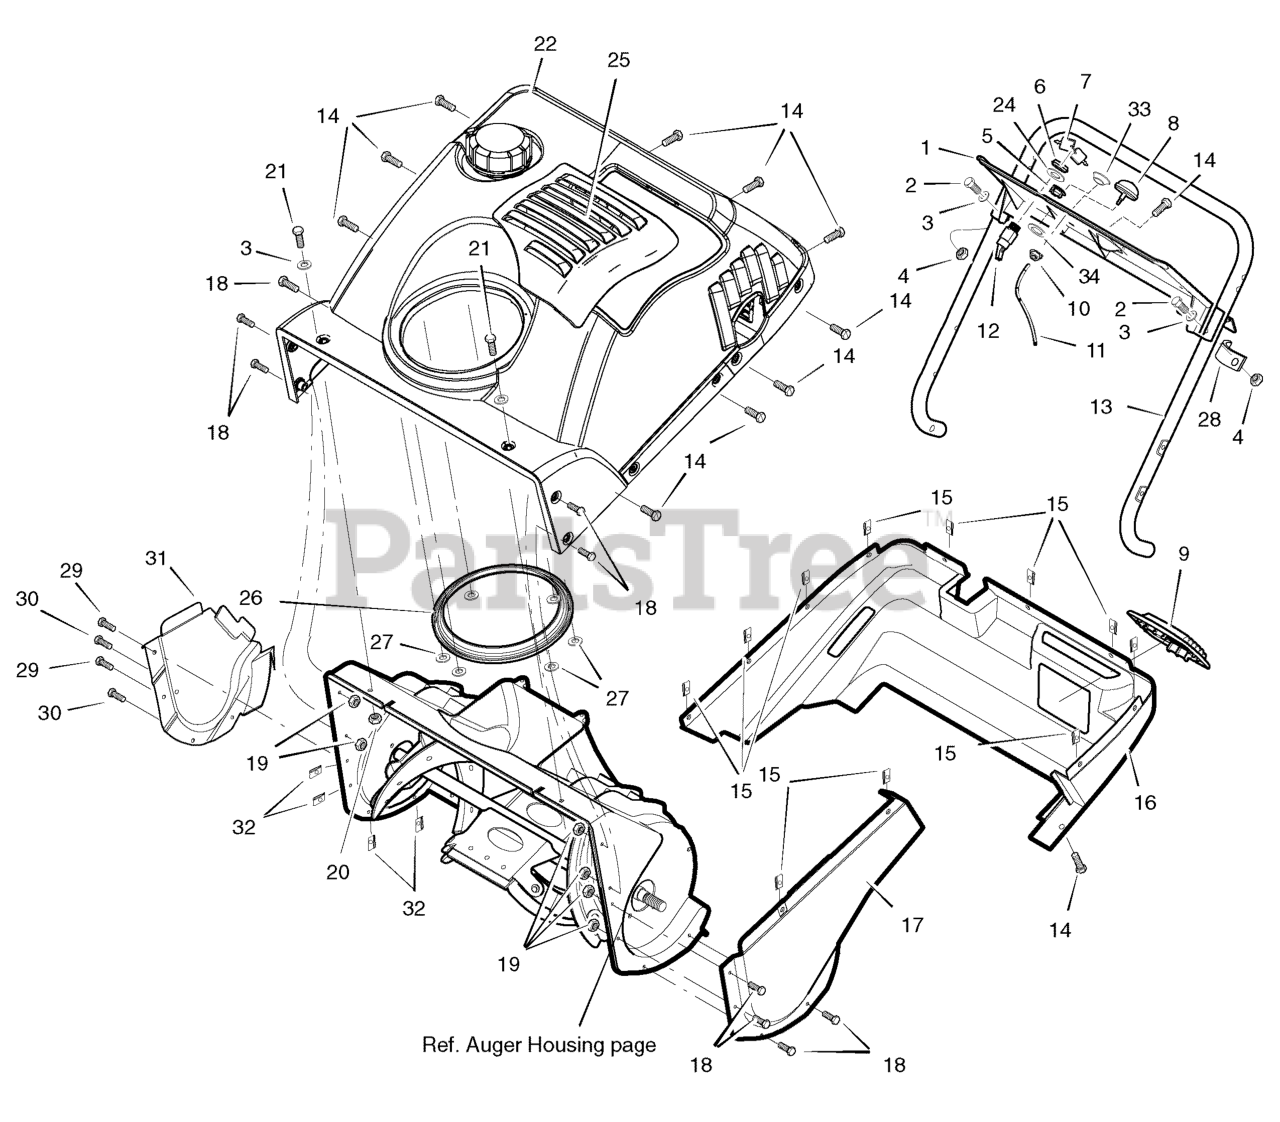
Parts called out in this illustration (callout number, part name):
1	PANEL, Control
2	SCREW, 1/4 - 20 x 1-1/4
3	WASHER
4	NUT, 1/4 - 20
5	BUSHING, Chute Crank
6	NUT, 5/8 - 32
7	KEYS & RING, Starter
8	BULB, Fuel Primer
9	COVER, Access
10	NUT, Keps 1/4 - 20
11	HOSE, Primer, 9.5"
12	SWITCH, Ignition
13	HANDLE, Lower
14	SCREW, 1/4 - 14 x 3/4
15	NUT, 1/4 - 10
16	COVER, Bottom
17	COVER, Belt
18	SCREW, 10 - 24 x 1/2
19	NUT, Hex Center Lock, 10 - 24
20	LOCKNUT, Hex 1/4 - 20
21	SCREW, 1/4 - 20 x 9/10
22	COVER, Top Assembly
25	COVER, Oil Access
26	Gasket, Chute Ring
27	NUT, Push Pal
28	CLIP, Cable
29	SCREW, 10-24 x .72
30	SCREW, 10-24 x .95
31	COVER, R.H. Auger Housing
32	J-NUT, 1/4-10
33	GROMMET, Rope
34	WASHER, Rope Grommet
